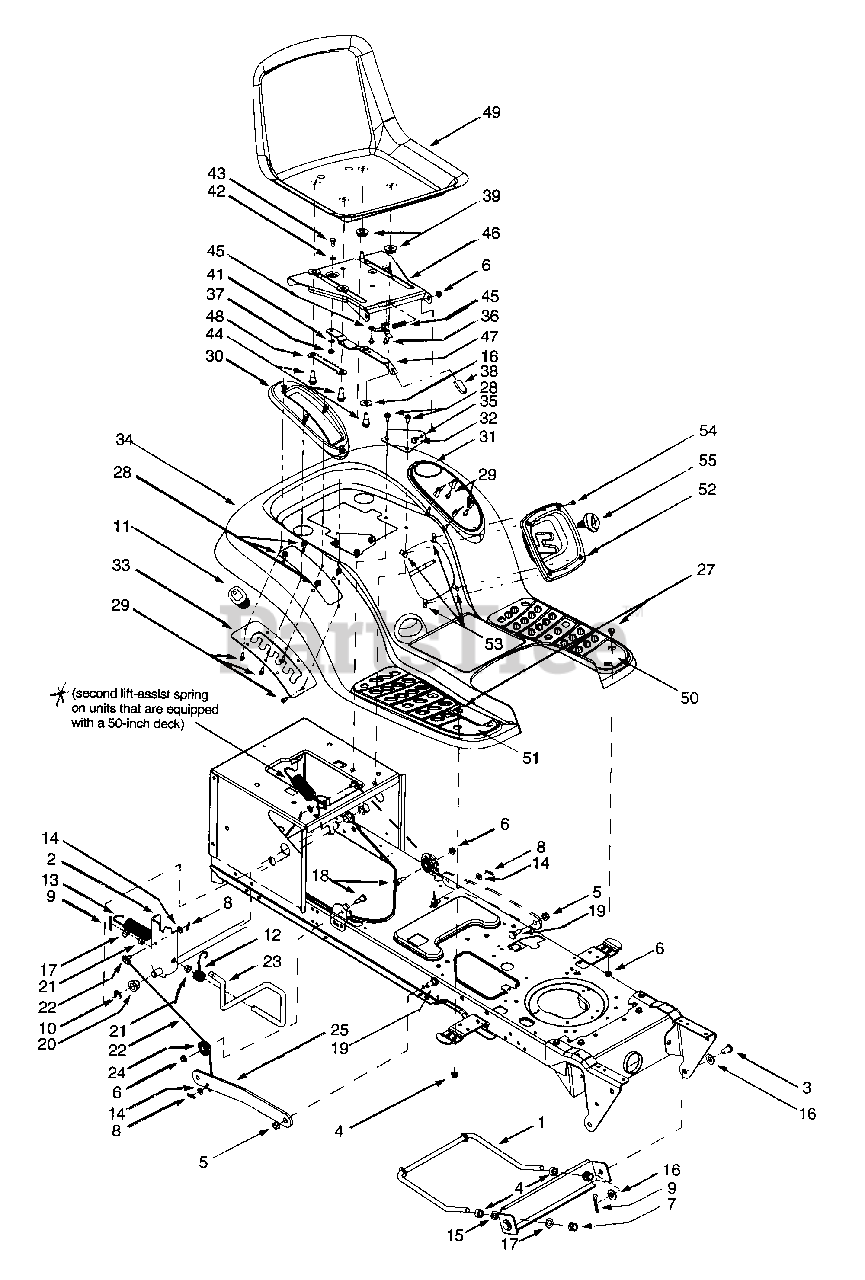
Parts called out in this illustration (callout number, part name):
1	Deck Stabilizer Rod
4	Hex Nut, 1/2-13
5	Flange Lock Nut, 3/8-16
6	Flange Lock Nut, 5/16-18
7	Hex Nut, 1/2-13
8	Internal Cotter Pin
9	Cotter Pin
10	E-ring
11	Handle Grip
12	Torsion Spring
13	Lift-assist Spring, 1.15 x 5.99
14	Flat Washer, 5/16
15	Lock Washer, 1/2
16	Flat Washer, .31 x 1.062 x .134
17	Flat Washer, .51 x 1.12 x .06
18	Hex Cap Screw, 5/16-18 x .62
19	Shoulder Screw, .5 x .27, 3/8-16
20	Hex Flange Bearing
21	Snap Flange Bearing
22	Lift Cable, 16.16
23	Lift Handle
24	Roller Pulley
27	Carriage Bolt, 5/16-18 x .62
28	Self Tapping Screw, 5/16-18 x .625
29	Self Tapping Screw, 1/4-15 x .75
30	Lift Lever Cover
31	Cover w/ Cup Holder
32	Shoulder Screw, .437 x 1.62
36	Screw, #10-16 x .375
37	Hex Flange Lock Nut, 1/4-20
38	Seat Adjuster Grip
39	Spacer
41	Spring Washer, .265 x .562 x .025
42	Flat Washer, .344 x .62 x .03
43	Shoulder Screw, .340 x .285,1/4-20
44	Shoulder Screw, .50 x .50, 3/8-16
45	Seat Stop
48	Seat Adjustment Selector
49	Seat, Radiant Yellow w/Drain Holes
50	LH Foot Pad
51	RH Foot Pad
52	Shift Cover
53	Speed Nut, 1/4-20
54	Phillips Screw, 1/4-20 x .75
55	Shift Knob
